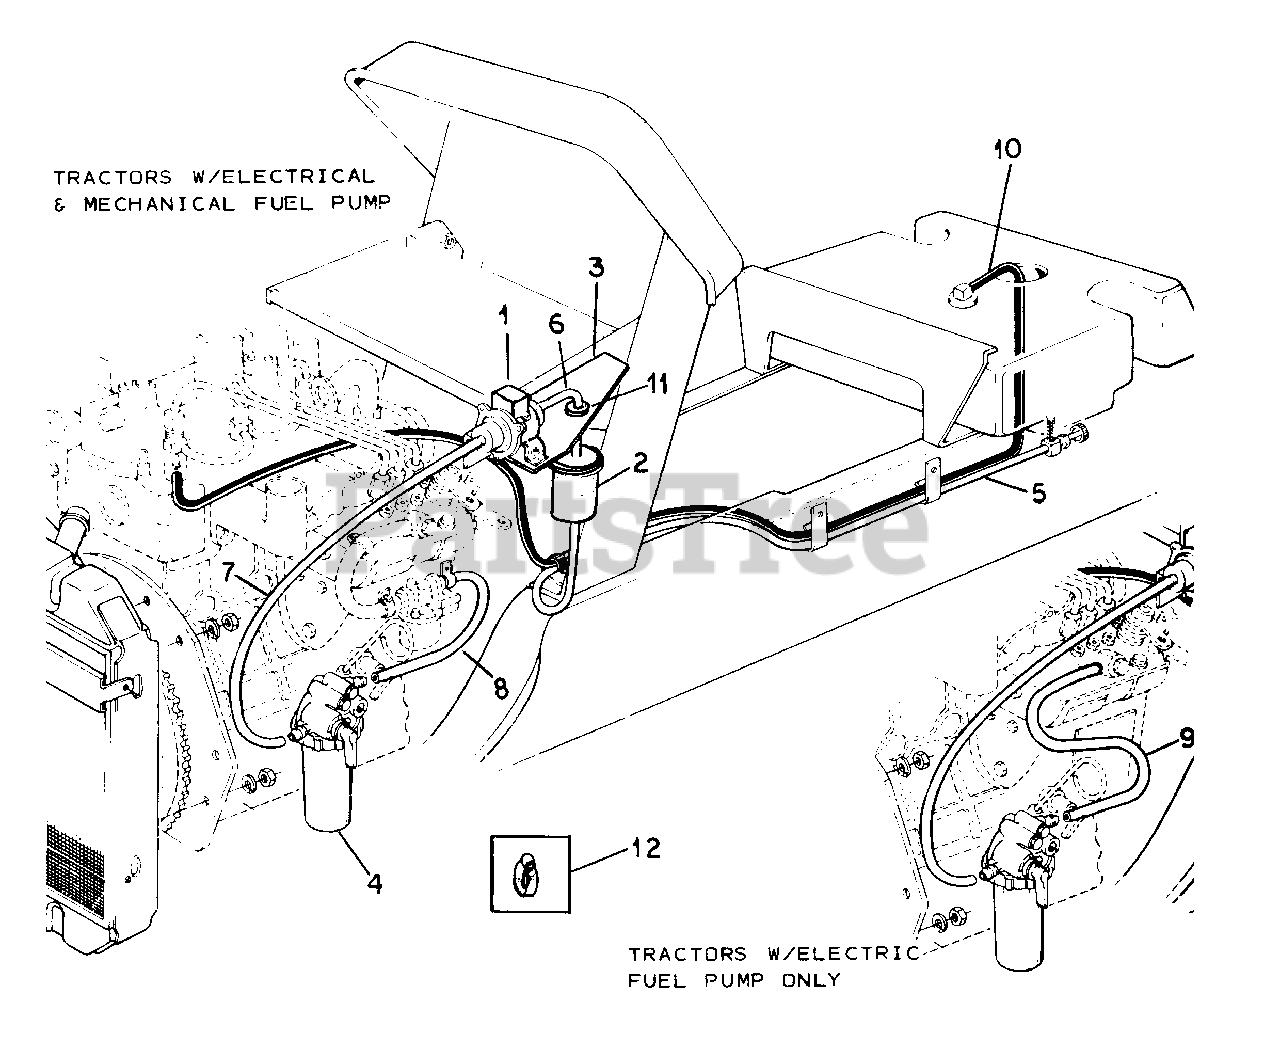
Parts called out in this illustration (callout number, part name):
1	Pump, Fuel, Electric
2	Filter, Fuel, Pre-Filter
3	Support, Fuel Pump
4	Filter, Fuel
5	Hose, Fuel Tank to Pre-Filter
6	Hose, Fuel Pre-Filter to Electric Pump
7	Hose, Fuel-Electric Pump to Fuel Filter
8	Hose, Fuel-Filter to Mechanical Pump
9	Hose, Fuel Filter to Injection Pump
10	Hose, Fuel-Engine to Tank Return
12	Clamp, Hose
